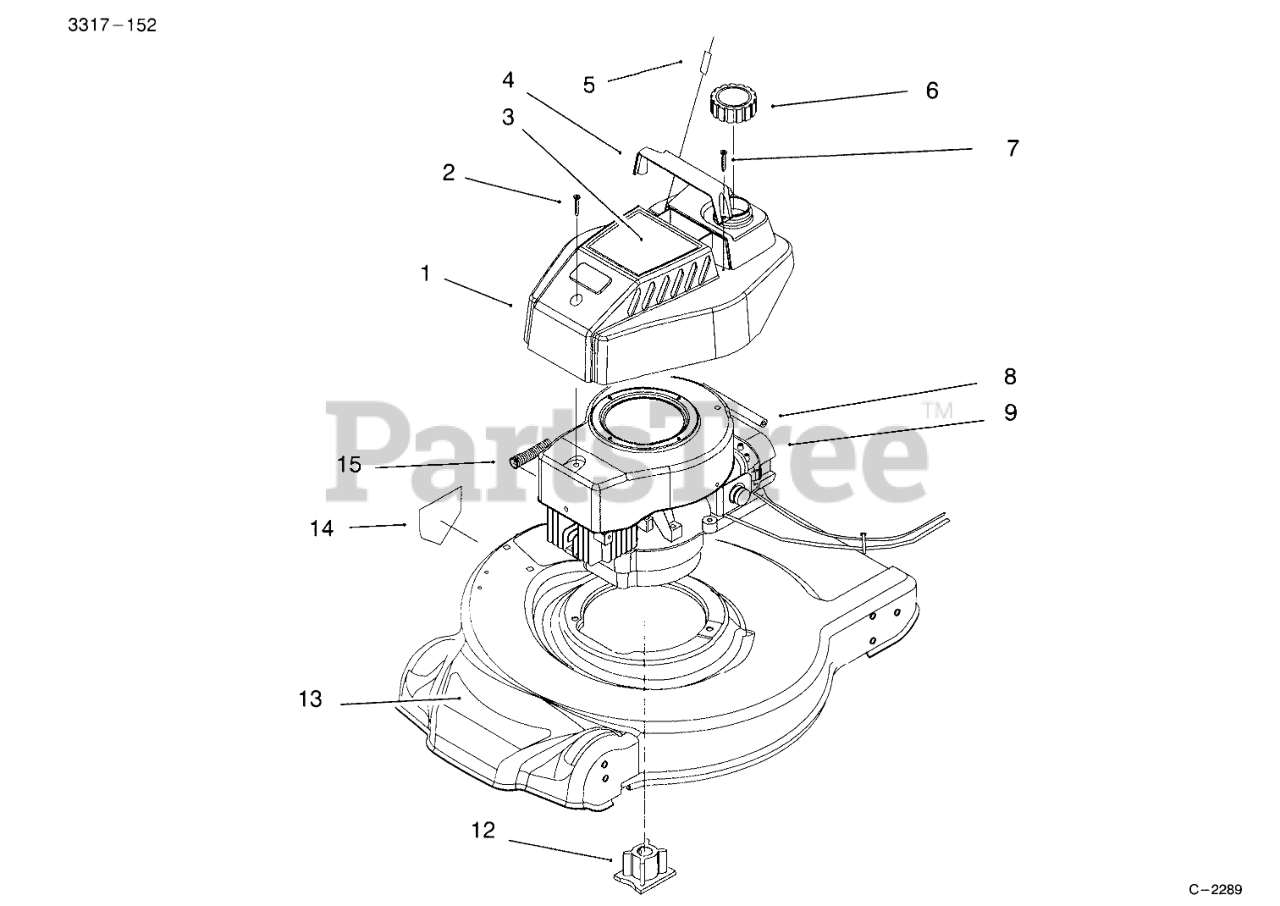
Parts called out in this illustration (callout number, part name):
1	TANK/SHROUD
2	SCREW
3	OBS EXCEPT FOR SERVICE DECAL - ENGINE
4	STRAP - TANK
5	STOP-ROPE
6	GAS CAP ASSEMBLY
7	SCREW-PPH
8	HOSE-FUEL
9	Engine (Model No. 20441 Only)
12	BLADE RETAINER
13	DECAL - DECK
14	DECAL-DANGER
15	SPRING-COMPRESSION
